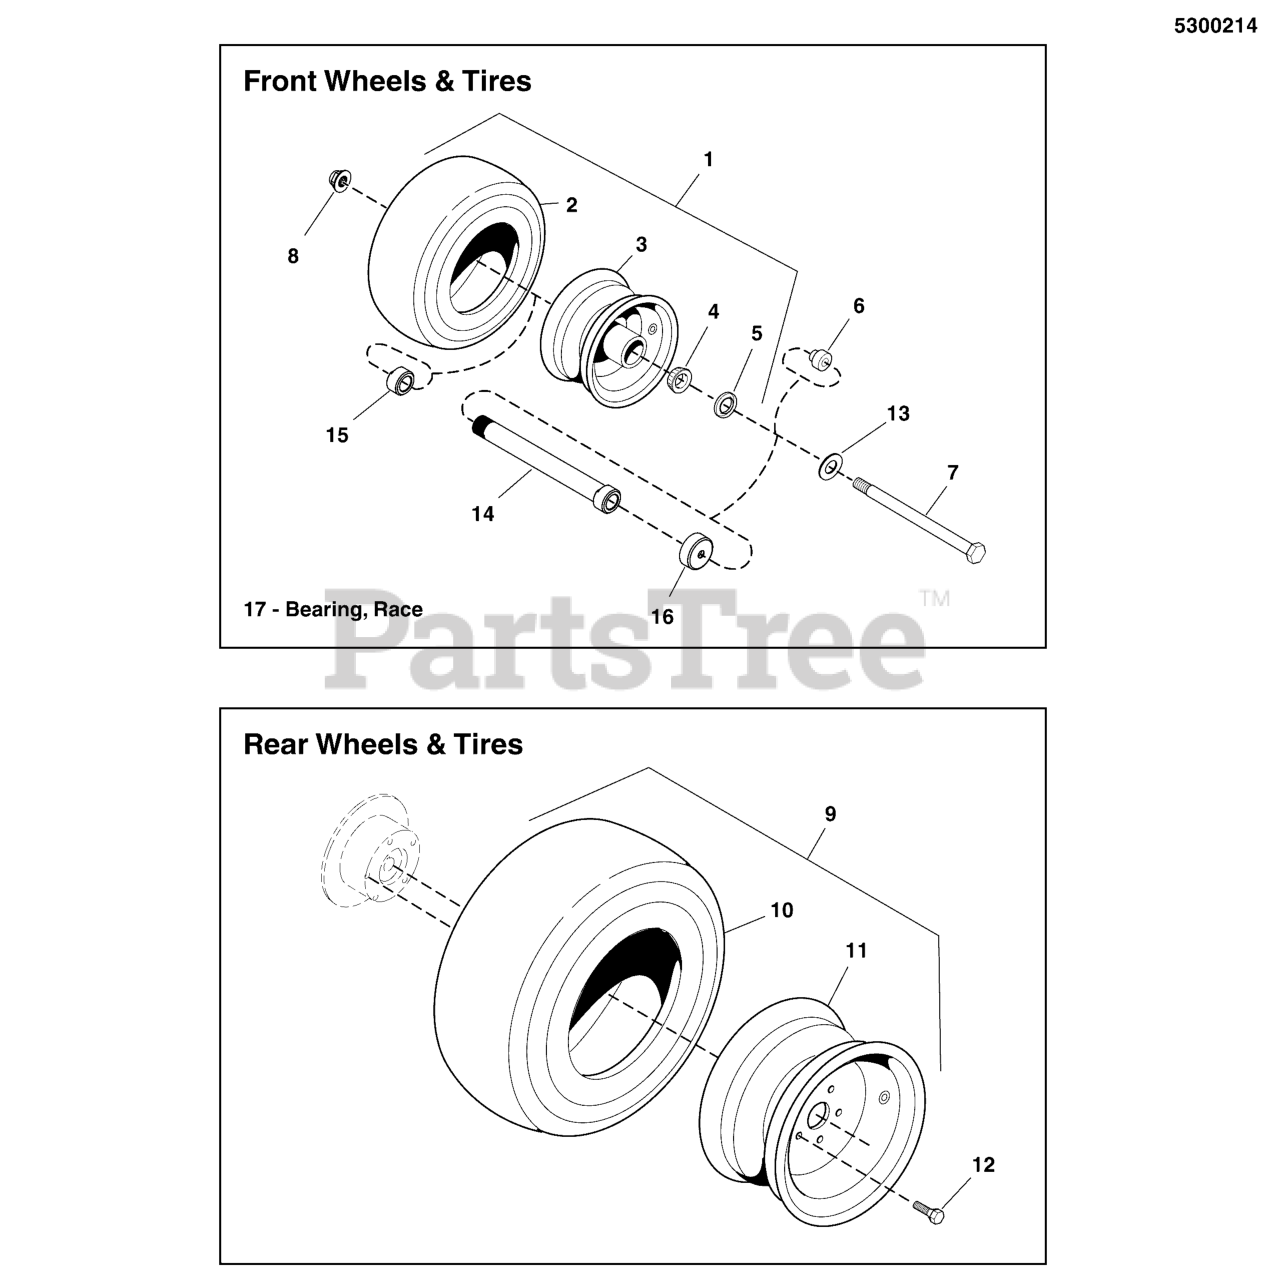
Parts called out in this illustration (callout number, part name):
1	TIRE ASSM, 13 X 6.5 - 6, PNE / TB
2	TIRE, RUBBER ONLY
3	WHEEL ASSEMBLY, for 13 x 6.5 x 6 Tires, Complete
4	BEARING, Tapered Roller
5	SEAL, GREASE
6	ADAPTER, CASTER AXLE, CZ
7	BOLT, 1/2-13 X 9" GD5 YZ
8	NUT, Hex Flange, Nylock, 1/2-13
9	WHEEL/TIRE ASSY, 26X12-12, 4PLY K505
10	TIRE, 26 X 12 - 12
11	Wheel, 12 X 9.5", 5 Hole
12	BOLT, WHEEL LUG, 1/2" X 1-5/8
13	WASHER, 1/2 SAE
14	BEARING ADJUSTER, SPACER, 7.062 LG
15	NUT, BEARING ADJUSTER, AXLE
16	DEBRIS COVER, CASTER WHEELS
